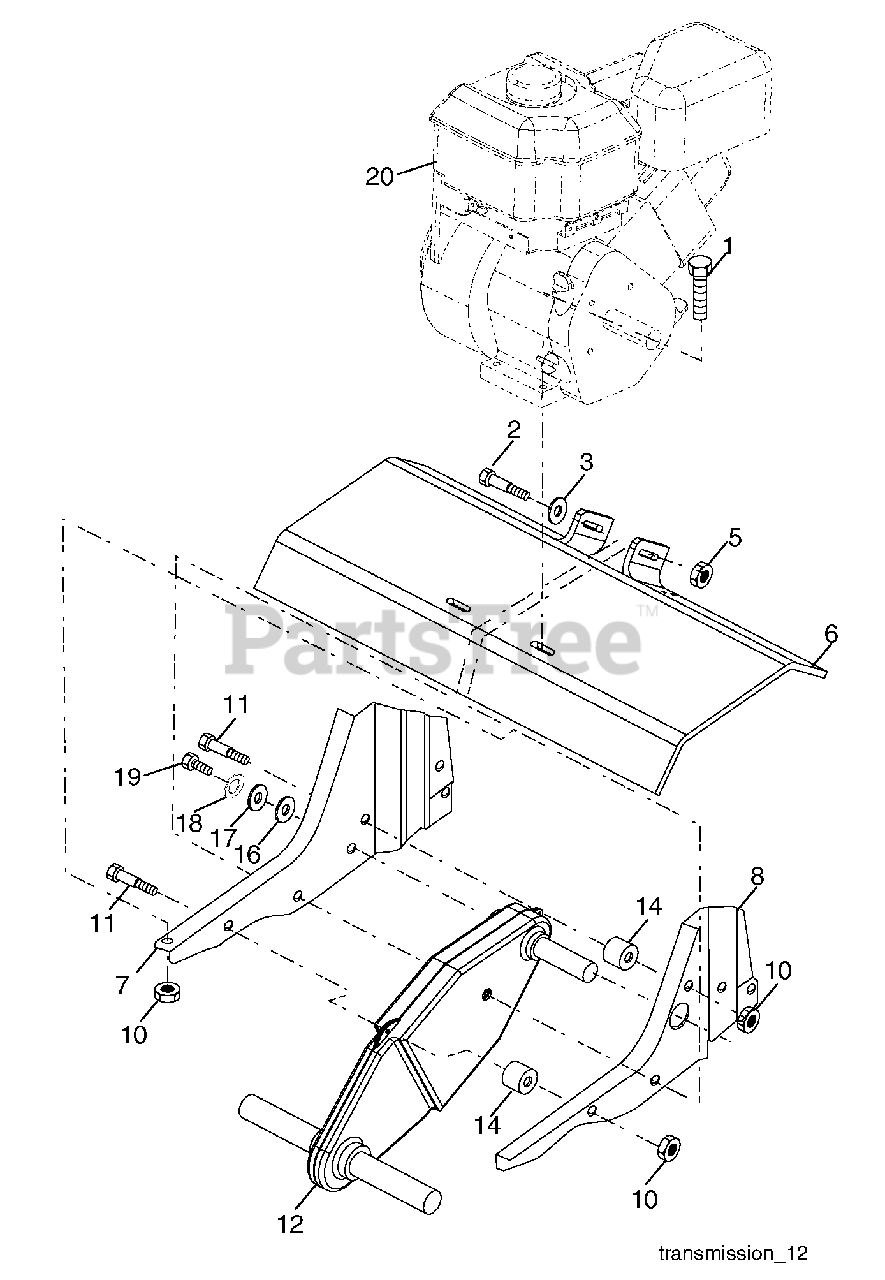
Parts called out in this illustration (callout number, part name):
1	Bolt, Hex 5/16-18 x 1-1/2 Gr. 2
2	Bolt, Hex 3/8-16 x 3-1/4
3	Washer 13/32 x 13/16 x 11
5	Locknut 3/8-16
6	Shield, Tine
7	Bracket, Engine, R.H.
8	Bracket, Engine, L.H.
10	Nut, Hex 5/16-18
11	Bolt, Hex Head 5/16-18 x 2.5
12	Transmission
14	Spacer, Split
16	Washer 9/32 x 7/8 x 12 Ga.
17	Washer 9/32 x 1-1/4 x 16 Ga.
18	Washer, Lock 1/4
19	Bolt, Hex 1/4-28 x 3/4 Gr. 5
